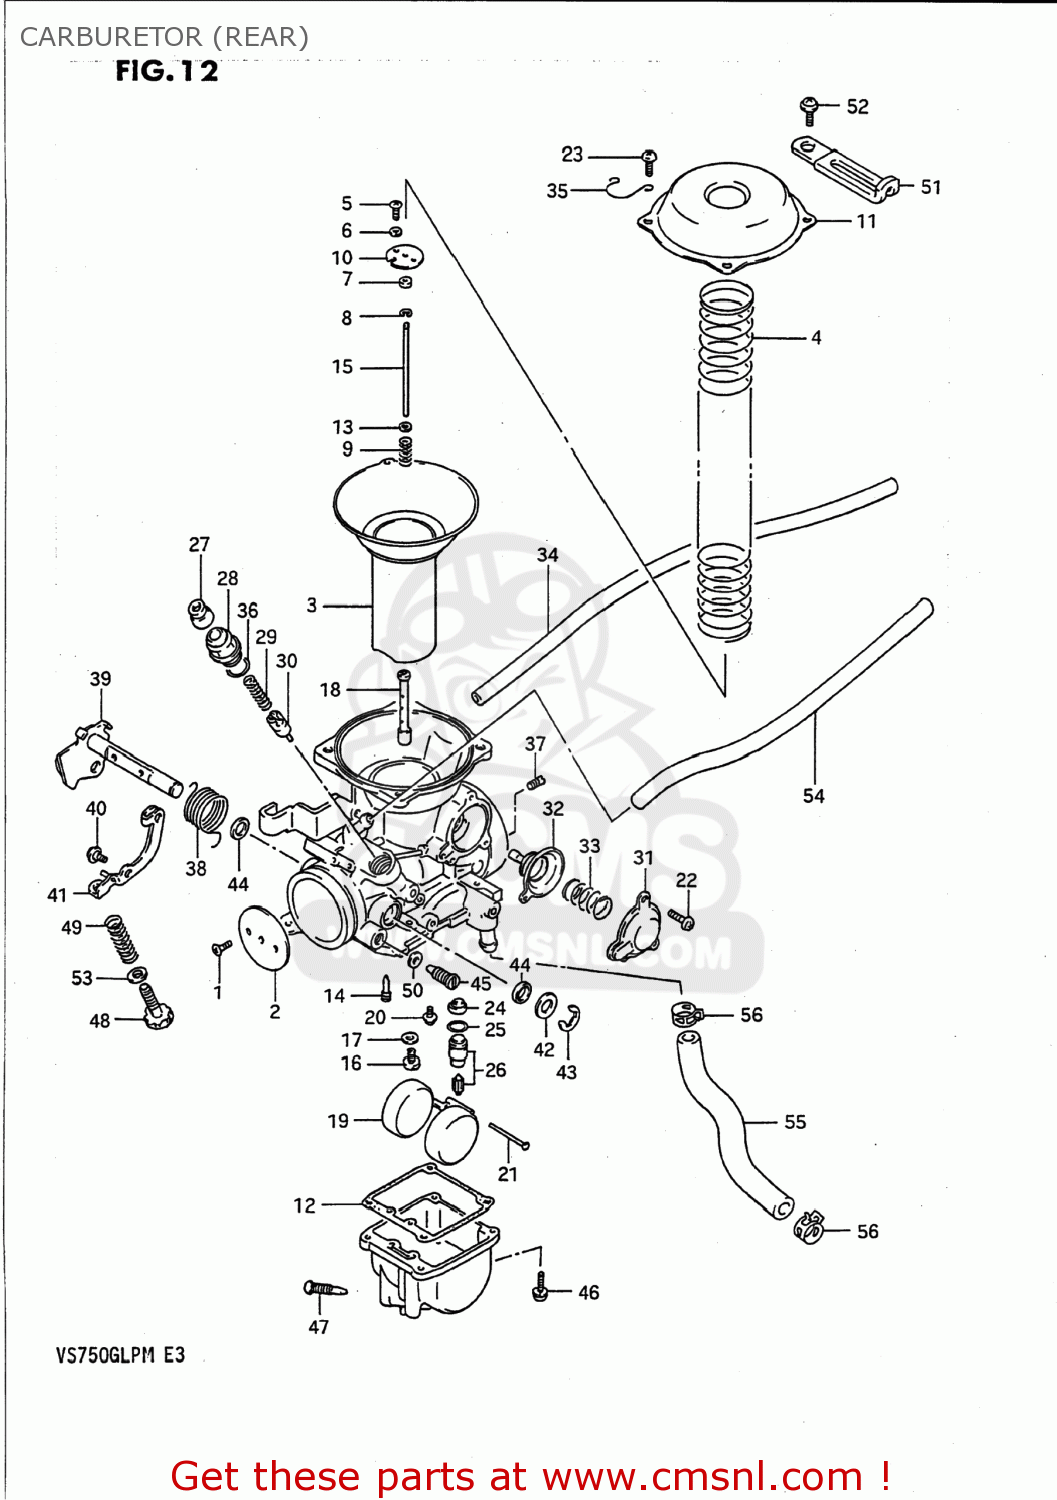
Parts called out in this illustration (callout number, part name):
1	SCREW
2	VALVE,THROTTLE
3	DIAPHRAGM,CARBURETOR
4	SPRING,DIAPHRAGM
5	SCREW
6	LOCK WASHER
7	RING
8	CLIP
9	SPRING
10	PLATE
11	COVER,DIAPHRAGM
12	GASKET,FLOAT CHAMBER (NAS)
13	WASHER
14	JET(40)
15	NEEDLE JET
16	JET,MAIN(132.5)
17	WASHER,NEEDLE NOZZLE
18	JET,NEEDLE
19	FLOAT
20	SCREW
21	PIN,FLOAT
22	SCREWM4X0.7X10
23	SCREW
24	FILTER
25	O-RING,NEEDLE VALVE
26	VALVE ASSY,NEEDLE
27	CAP
28	HOLDER,GUIDE
29	SPRING
30	PLUNGER
31	COVER
32	DIAPHRAGM ASSY
33	SPRING
34	HOSE
35	CLIP
36	O RING
37	JET,AIR(65)
38	SPRING,SHAFT RETURN
39	SHAFT ASSEMBLY
40	SCREW
41	LEVER,ASSY
42	GASKET,THROTTLE SHAFT (NAS)
43	E RING
44	SEAL,THROTTLE SHAFT
45	SCREW
46	SCREW
47	PLUG,DRAIN
48	ADJUSTER
49	SPRING
50	WASHER
51	CLIP
52	SCREW
53	WASHER
54	HOSE
55	HOSE
56	CLIP
